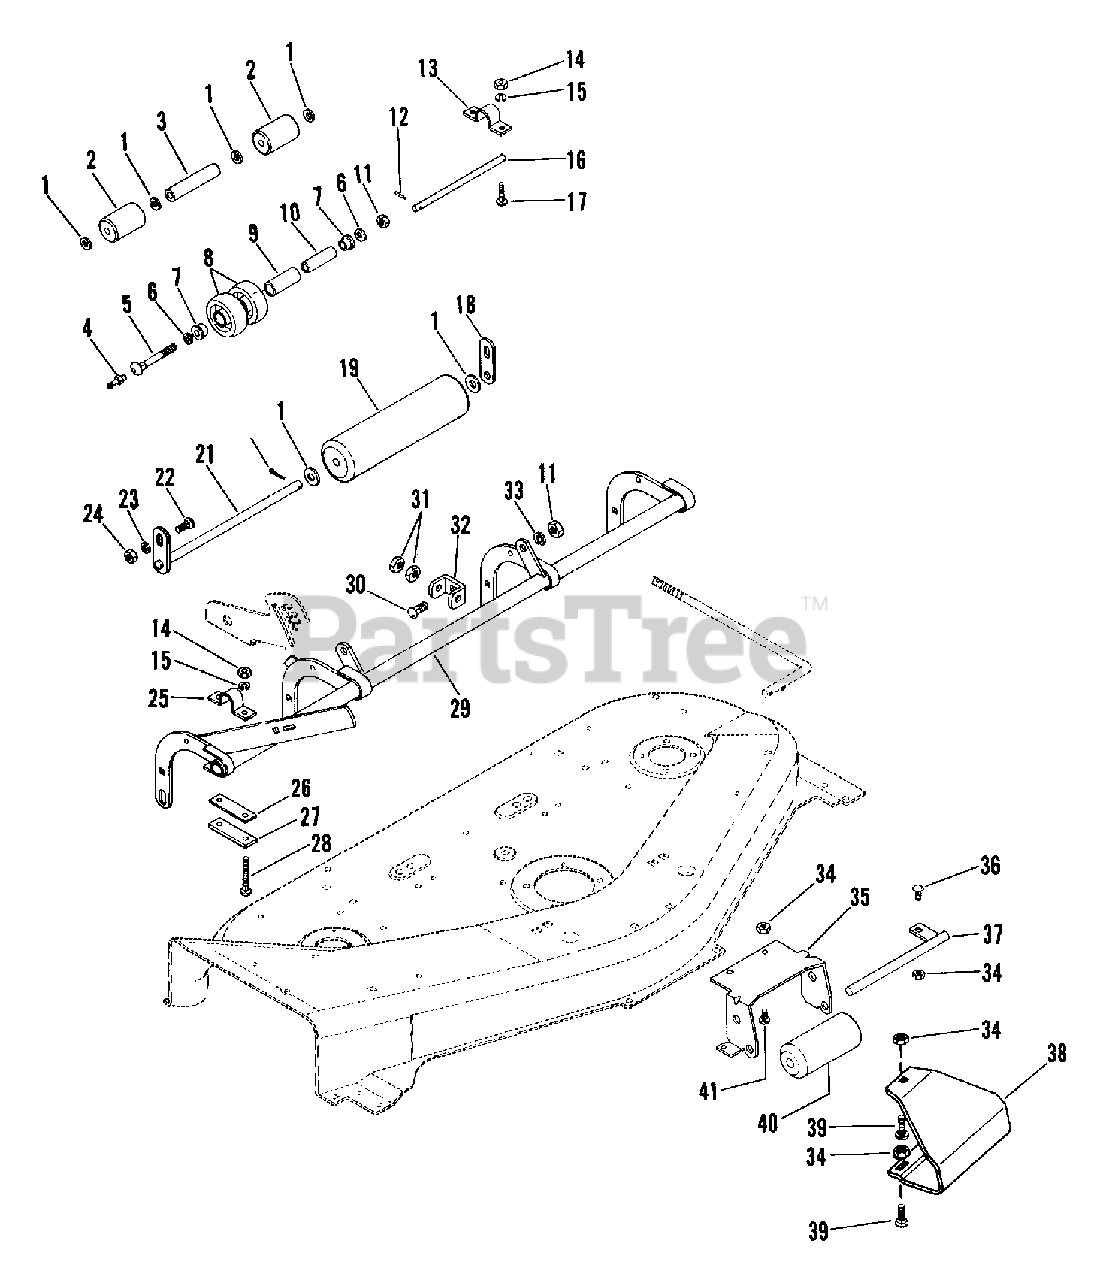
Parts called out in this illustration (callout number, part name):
1	WSHR-FL-STL.656X1.312X.095 PL
2	ROLLER
3	SPACER .726X.875X6.375
4	SPIN DRIVE ZERK FITTING
5	WHEEL BOLT W/ZERK
6	WSHR-FL-STL .511X1.441X.125 PL
7	BRG-BALL .500X1.125X.500
8	WHL 5 IN O.D.
9	WHEEL HUB
10	SPACER .512X.747X3.396
11	NUT-LK-CTR .50-13
12	PIN-ROLL .250X1.00
13	ROLLER CLAMP
14	NUT-HEX .312-18
15	WSHR-LK .312X.097 PL HVY
16	SHAFT
17	BLT-RDHDSQNK .31-18X.75 GR5 PL
18	LINK
19	ROLLER
20	PIN-COTR .18X1.0 PL
21	ROLLER SHAFT
22	BLT-RDHDSQSHNK .38-16X1.00 PL
23	WSHR-FL-STL .438X1.0X.083 PL
24	NUT-LK-CTR .375-16 GR A PL
25	CLAMP
26	ADJUSTMENT PLATE
26	PAD
27	ADJUSTMENT PLATE
28	BLT-RDHDSQNK .31-18X1.38SHT PL
28	BLT-RDHDSQNK .31-18X2.75 SHPL
28	BLT-RDHDSQNK .31-18X1.0 SHT PL
29	ROLLER FRAME
29	ROLLER FRAME 42 INCH
30	BLT-RDHDSQNK .50-13X1.25 PL
31	NUT .50-13 PL
33	WSHR-FL-STL .505X.880X.072 PL
34	NUT-LK .312-18 GR A PL
34	BRACKET ROLLER
35	BRACKET, ROLLER
36	BLT-RDHDSQNK .31-18X.75 GR5 PL
36	ROLLER SHAFT
37	ROLLER SHAFT
38	SKID 42 INCH MOWER
39	BLT-RDHDSQSHNK .31-18X.50 YZ
40	ROLLER
41	BLT-RDHDSQNK .312-18X.62 PL
